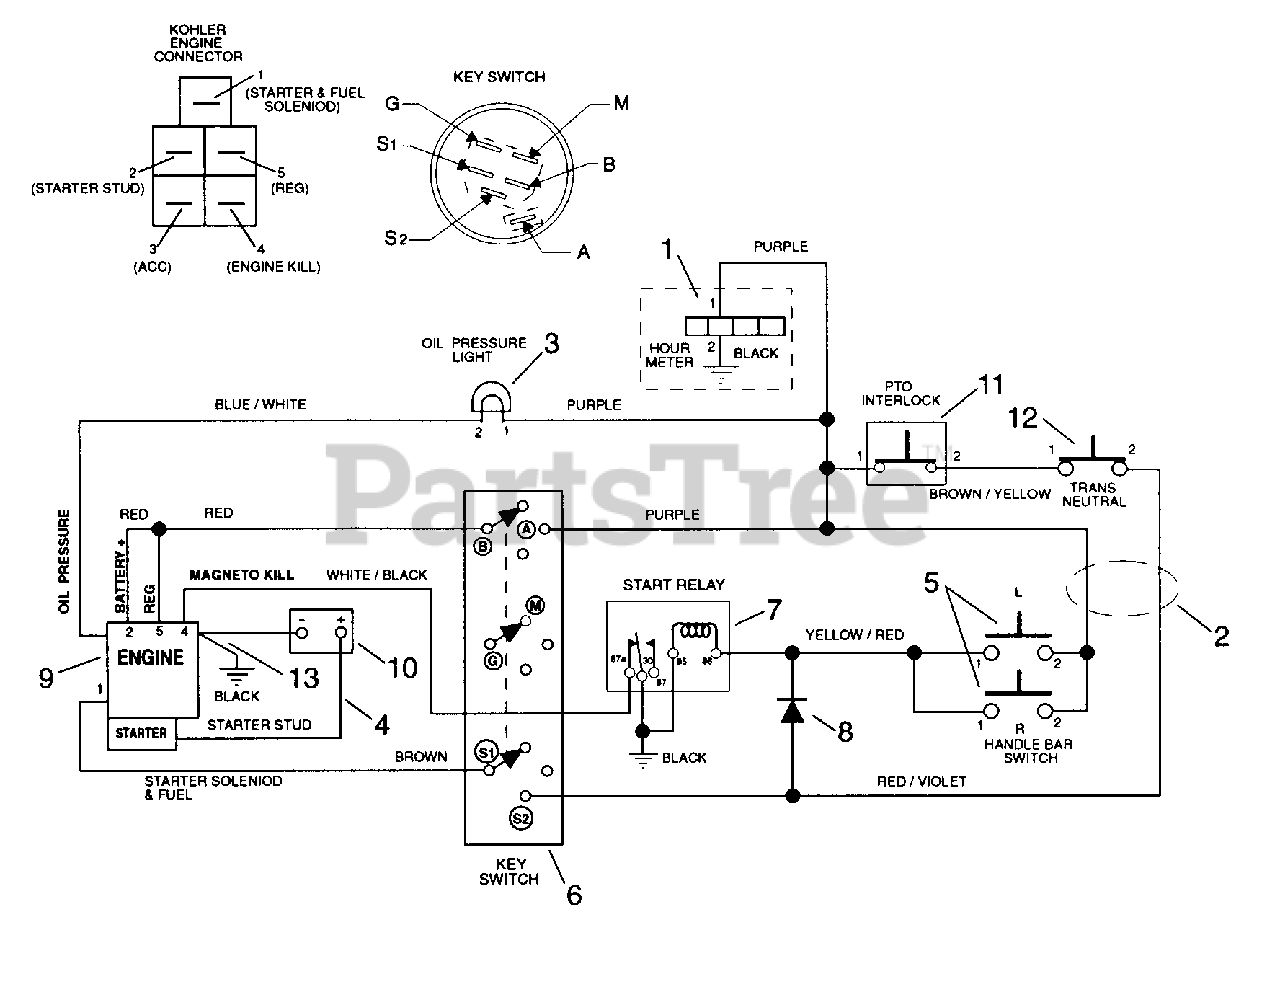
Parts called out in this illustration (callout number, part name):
1	Hour Meter
2	Wire Harness, PRO-300 CV18
3	Light, Indicator
4	Cable, Starter
5	Switch
6	Ignition Switch Assembly
7	Relay
8	Molded Diode Plug - Clear 1 AMP
9	Engine, Kohler CV18
10	Battery, 12 Volt
11	Switch - Neutral Start N.O.
12	Switch, Interlock
13	Cable, Negative Battery
